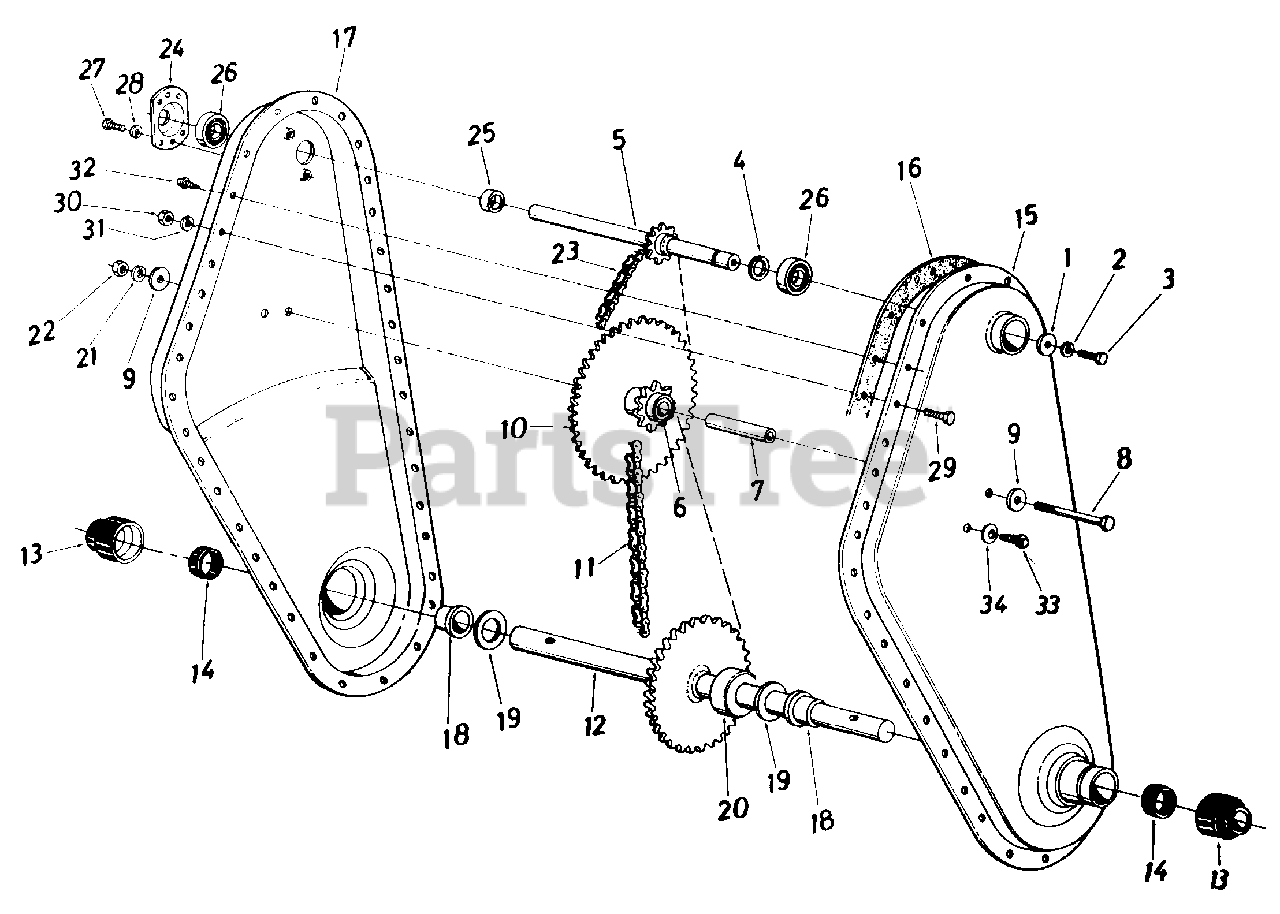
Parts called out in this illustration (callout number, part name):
1	Fl-Wash. 1/4" I.D. x .93" O.D. x .120
2	L-Wash. 1/4" I.D.*
3	Hex Bolt 1/4-28 x .62" Lg. w/ Patch
4	External Snap Ring 5/8" Dia.
5	Input Shaft Ass'y.
6	Bearing 5/8" I.D. x 3/4" O.D. x 1.860" Lg.
7	Sprocket Hub Tubing 3/8" I.D. x 5/8" O.D. x 1.90
8	Hex Bolt 3/8-24 x 2.75" Lg.*
9	Fl-Wash. 3/8" I.D. x 1.25" O.D. x .10
10	Sprocket Ass'y.
11	#50 Chain 5/8" Pitch x 46 0 Links Endless
12	Tine Shaft Ass'y.
13	Dust Cup
14	Seal Ring Single Lip Springless
19	Fl-Thrust Wash. 1.0" I.D. x .03 Thk.
20	Step Spacer
21	L-Wash. 3/8" I.D.
22	Hex Nut 3/8-24 Thd.
23	#35 Chain 3/8" Pitch x 52 Links Endless
24	Bearing Housing 1.38" I.D.
25	Spacer
26	Ball Bearing .625" I.D. x 1.38" O.D. x .437
27	Hex Wash. SF-Tap Scr. 1/4-20 x .50" Lg.
28	L-Wash. 1/4" I.D.*
29	Hex Bolt 5/16-18 x .75" Lg.*
30	Hex Nut 5/16-18 Thd.*
31	L-Wash. 5/16" I.D.*
32	Hex Wash. SF-Tap Scr. 1/4-20 x .50" Lg.
33	Hex Wash. Hd. Tap Scr. 1/4-20 x .38" Lg.
34	Bell-Wash. .265" I.D. x .751' O.D.
